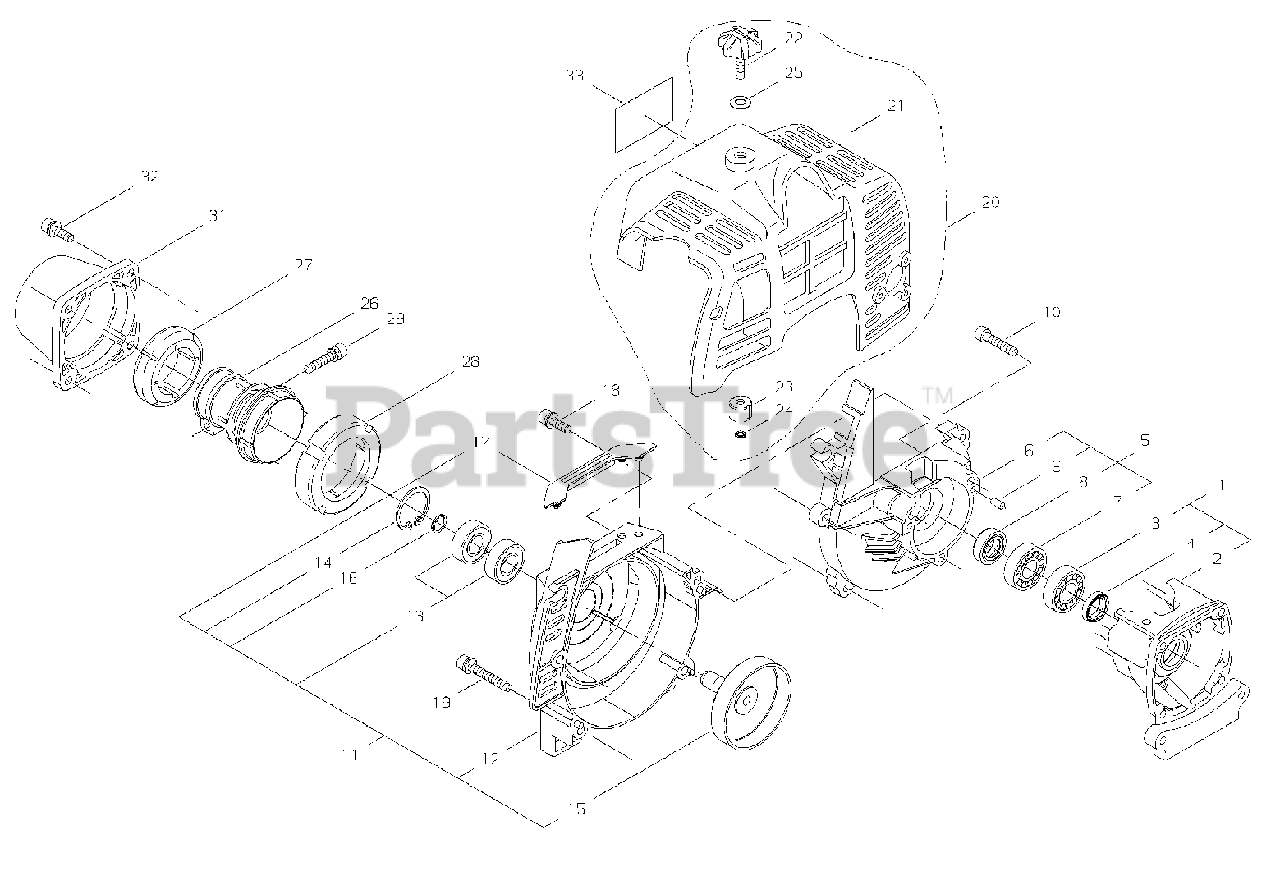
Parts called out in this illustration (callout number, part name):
2	CRANKCASE S
3	BEARING, BALL 6001 C3
4	SEAL, OIL 12
5	CRANKCASE ASSY, M
6	CRANKCASE M
7	BEARING, BALL 6001 C3
8	SEAL, OIL 12
9	PIN, LOCATING Ø4×8
10	BOLT 5×25
11	COVER ASSY, FAN
12	COVER, FAN
13	BEARING, BALL 6000ZZ
14	RING, SNAP Ø26
15	DRUM, CLUTCH
16	RING, SNAP WR10
17	CUSHION
18	BOLT M5×16
19	BOLT M5×45
20	COVER ASSY, CYLINDER
21	COVER, ENGINE
22	THUMBSCREW
23	INSULATOR 5 MM
24	CLIP
25	WASHER, CONE M6
26	CUSHION, AV
27	CUSHION, FRONT
28	HOLDER, REAR CUSHION
29	BOLT M5×25
31	COVER, AV CUSHION (RED)
32	BOLT M5×16
33	LABEL
